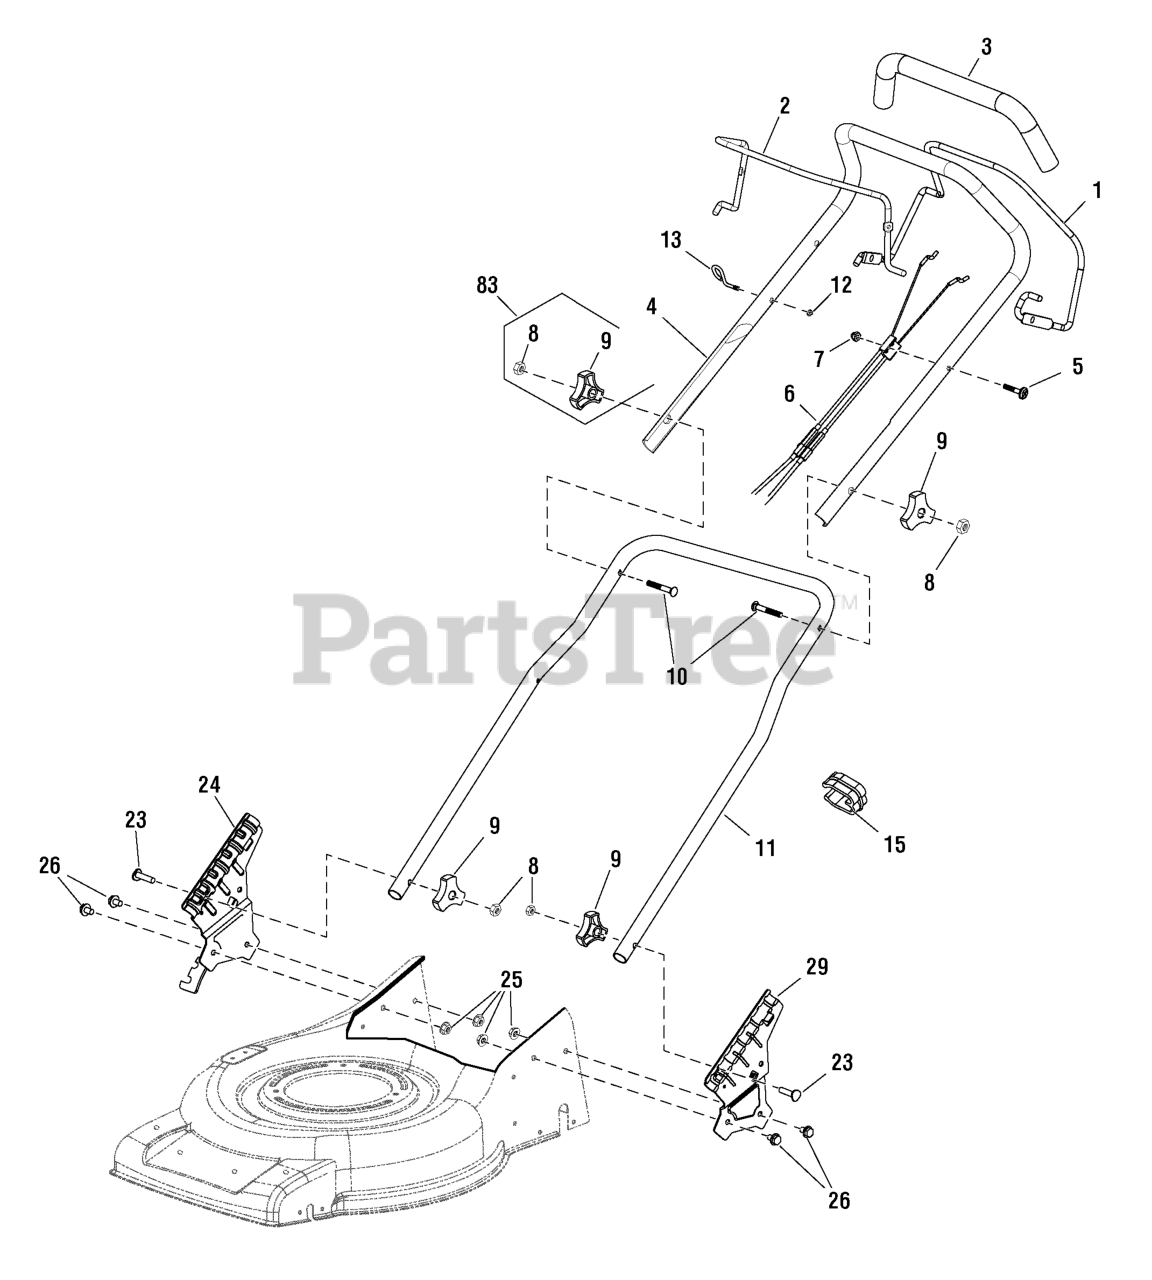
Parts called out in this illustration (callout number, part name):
1	BAIL, Drive
2	BAIL, Engine
4	HANDLE, Upper
5	BOLT, M6 x 35
6	CABLE, Brake
7	NUT, Acorn, M6
8	NUT, M8
10	BOLT, Carriage, M8 x 45
11	HANDLE, Lower
12	NUT, M6
13	ROPE GUIDE
15	CLIP, Cable
23	BOLT, Arc Head
24	BRACKET, Handle, Right
25	NUT, Hex, M8
26	BOLT, Hex Flange, M8 x 16
29	BRACKET, Handle, Left
83	KIT, Hardware, Knob
